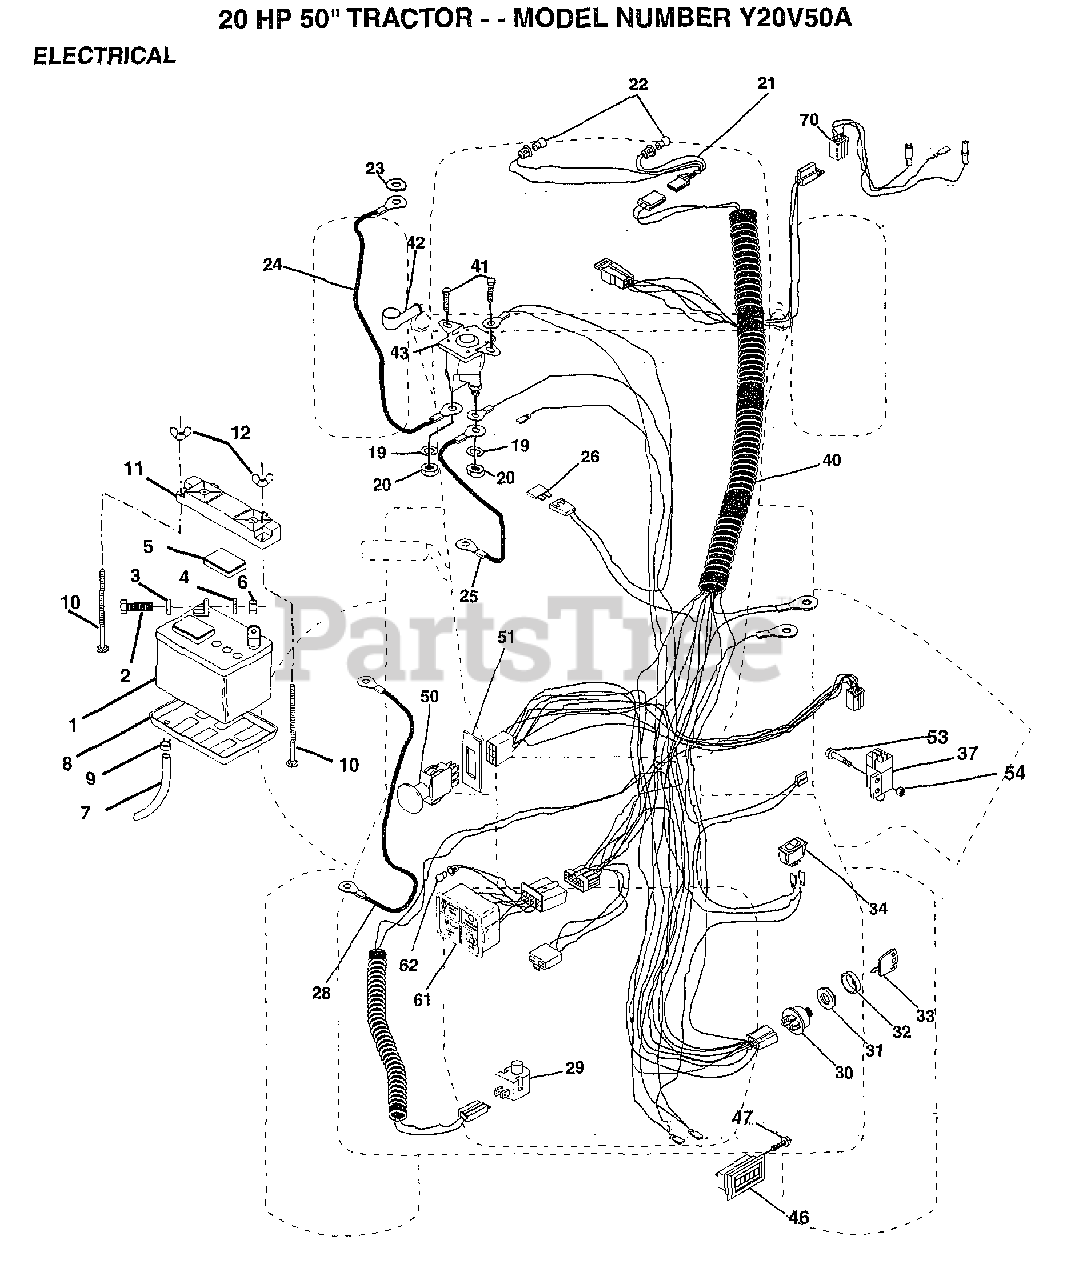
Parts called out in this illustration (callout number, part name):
2	BOLT LT
3	LOCKWASHER
4	WASHER
5	"CAP,BATTERY "
7	"DRAIN TU T, BATT"
8	"TRAY T, BATTERY"
9	HOSE CLAMP T
10	BOLT
20	NUT
21	"HARNESS,LIGHT SOC"
22	HEADLAMP BULB
23	LOCKWASHER
24	CABLE-BATTERY T
25	CABLE-BATTERY T
26	FUSE HYT
28	CABLE T
29	SWITCH SEAT
32	COVER KEY SWITCH
33	KEY MLD GEN DELTA
34	SWITCH LT
37	SWITCH INTERLOCKT
40	HARNESS IGNITION
41	SCREW
46	HOUR METER T
47	SCREW
51	RING RETAIN PTO
53	SCREW
54	"NUT,KEPS"
61	LIGHT.PKG.ASM.
62	BULB LIGHT T
70	HARNESS.ENG.VANII
